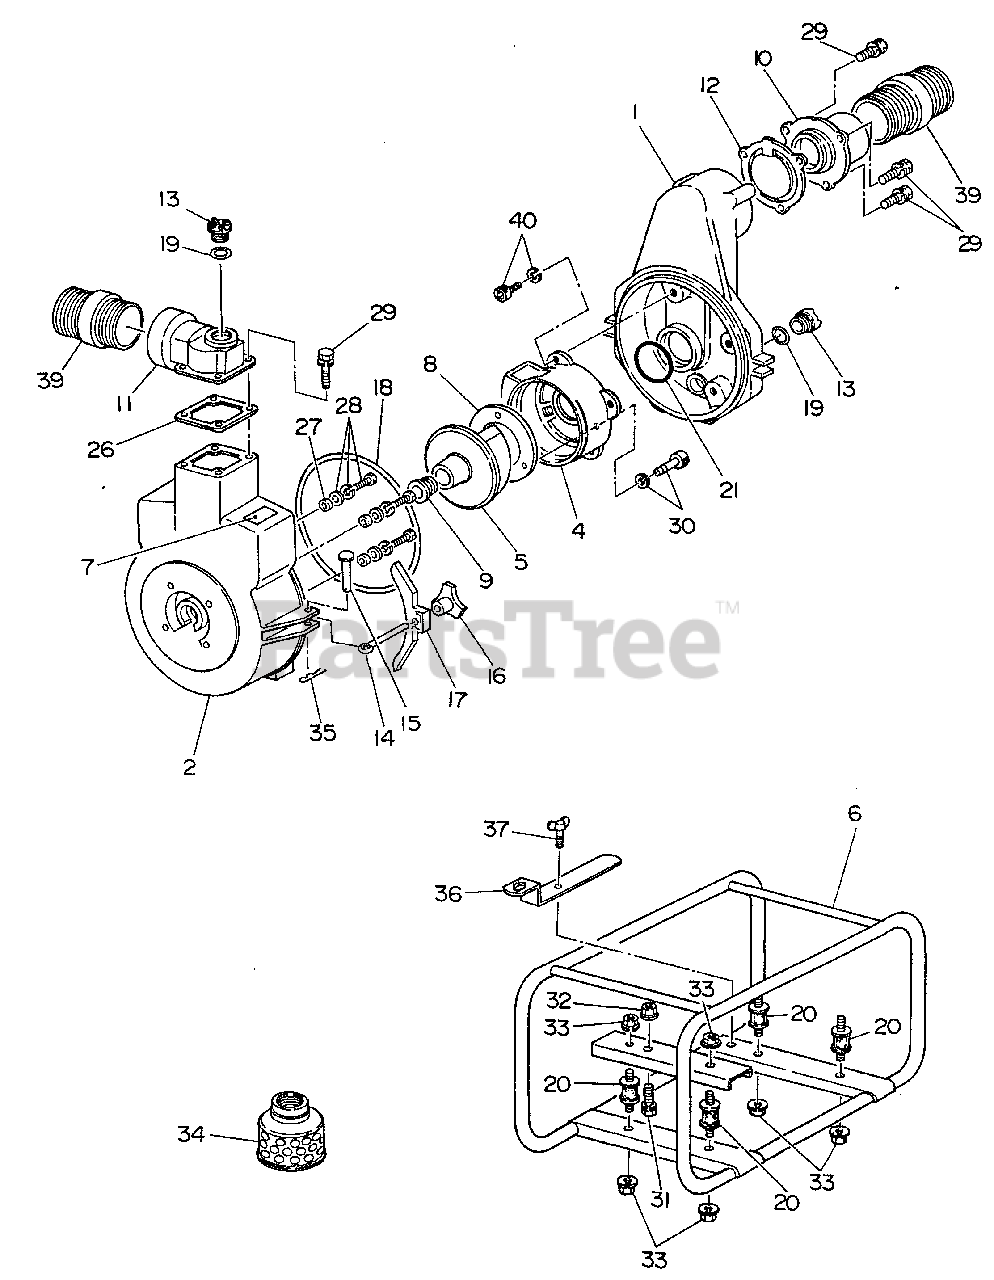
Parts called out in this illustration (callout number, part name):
1	CASING
2	COVER, CASING
4	INNER CASING
5	IMPELLER
6	FRAME
7	LABEL - PUMP
8	LINER
9	SEAL
10	SUCTION FLANGE
11	DELIVERY FLANGE
12	VALVE, CHECK
13	PLUG
14	COVER, BOLT
15	RIVET
16	KNOB
17	HOLDER, CASING COVER
19	O-RING
20	CUSHION
21	O-RING
26	PACKING
28	BOLT - 4X48
29	BOLT - 10X30
30	SCREW - 6X20
31	BOLT - 10X45
32	NUT - 10 -- FLANGE
33	NUT - 8
34	STRAINER, DEBRIS
35	PIN - SPRING
36	SUPPORT
37	THUMBSCREW
39	NIPPLE (NPTxNPT)
40	BOLT - 8X30
